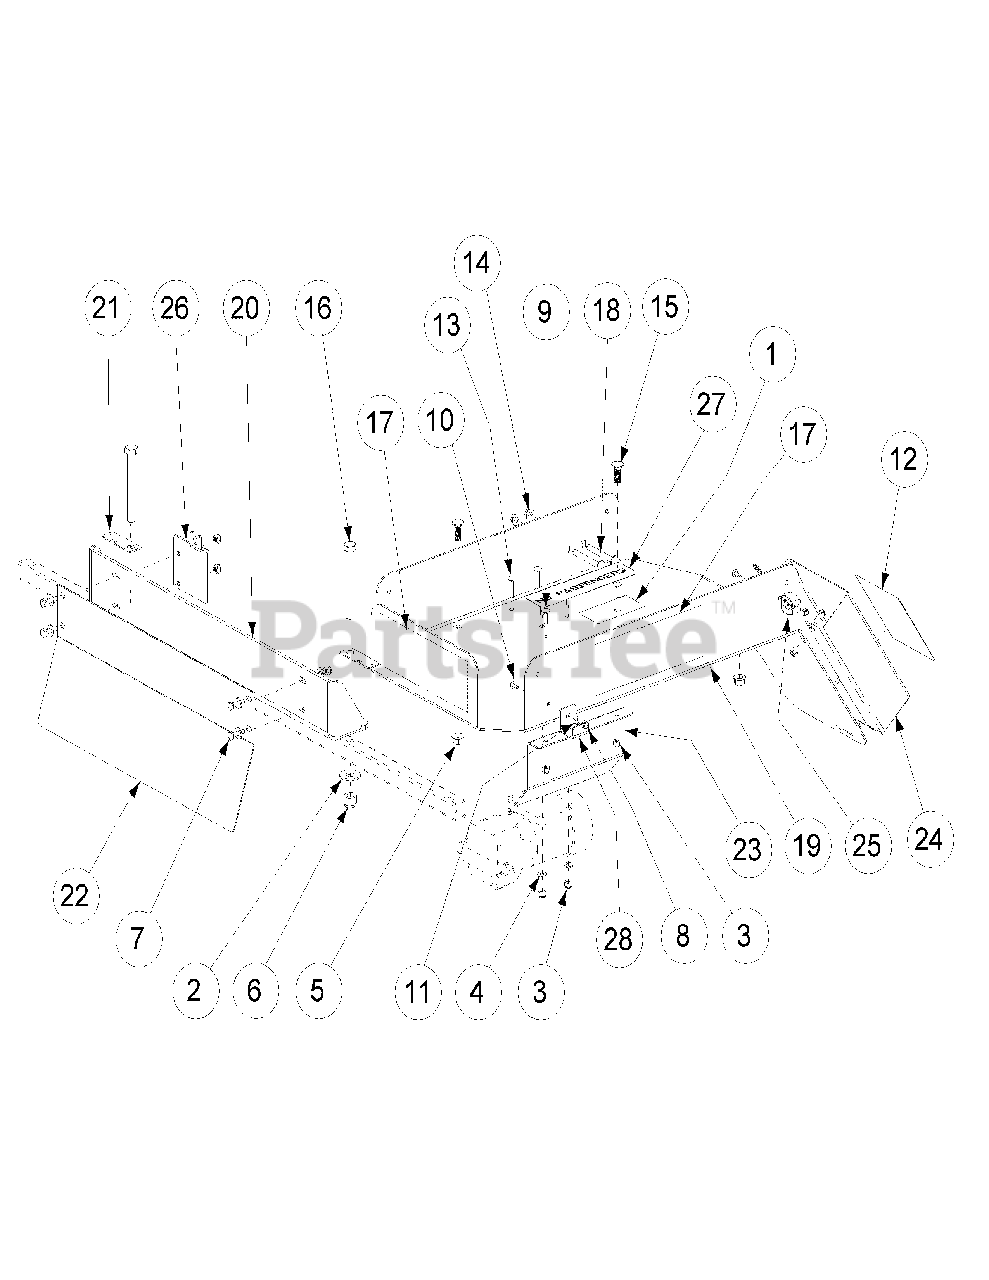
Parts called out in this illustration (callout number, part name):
1	Decal, 80# Capacity
2	Flat Washer, 1/2 Zinc
3	Lock Nut, Nylon Insert, 1/4-20
4	Flat Waser, 1/4 Zinc
5	Hex Nut, 3/8-16 Flange Lock
6	Lock Nut, Nylon Insert, 1/2-13
7	Hex Cap Screw, 1/4-20 x 1.25
8	Nut, Lock, Nylon Insert, #10-32
9	Carriage Bolt, 1/4-20 x 3/4
10	Machine Screw, 10-32 x 1/2
11	Flat Washer, #10, SS
12	Decal, Safety Procedures
13	Carriage Bolt, 1/4-20 x 1.00
14	Nut, Lock, HexFlange, 5/16-18
15	Carriage Bolt, 3/8-16 x 0.75 Long
16	Hex Head Capscrew, 1/2-13 x 4.00
17	Decal, Cub Cadet Commercial
18	Carriage Bolt, 5/16-18 x 2.75
19	Pump Motor PLate
20	Rear Spray Bumper
21	Boom Spring Plate
22	Boom Spray Shield
23	Electric Pump Cover
24	Spray Wand Hose Holder
25	Tool Holder
26	Deflector Cable Mounting Bracket
27	Decal, No Passengers
28	Stop Bracket
